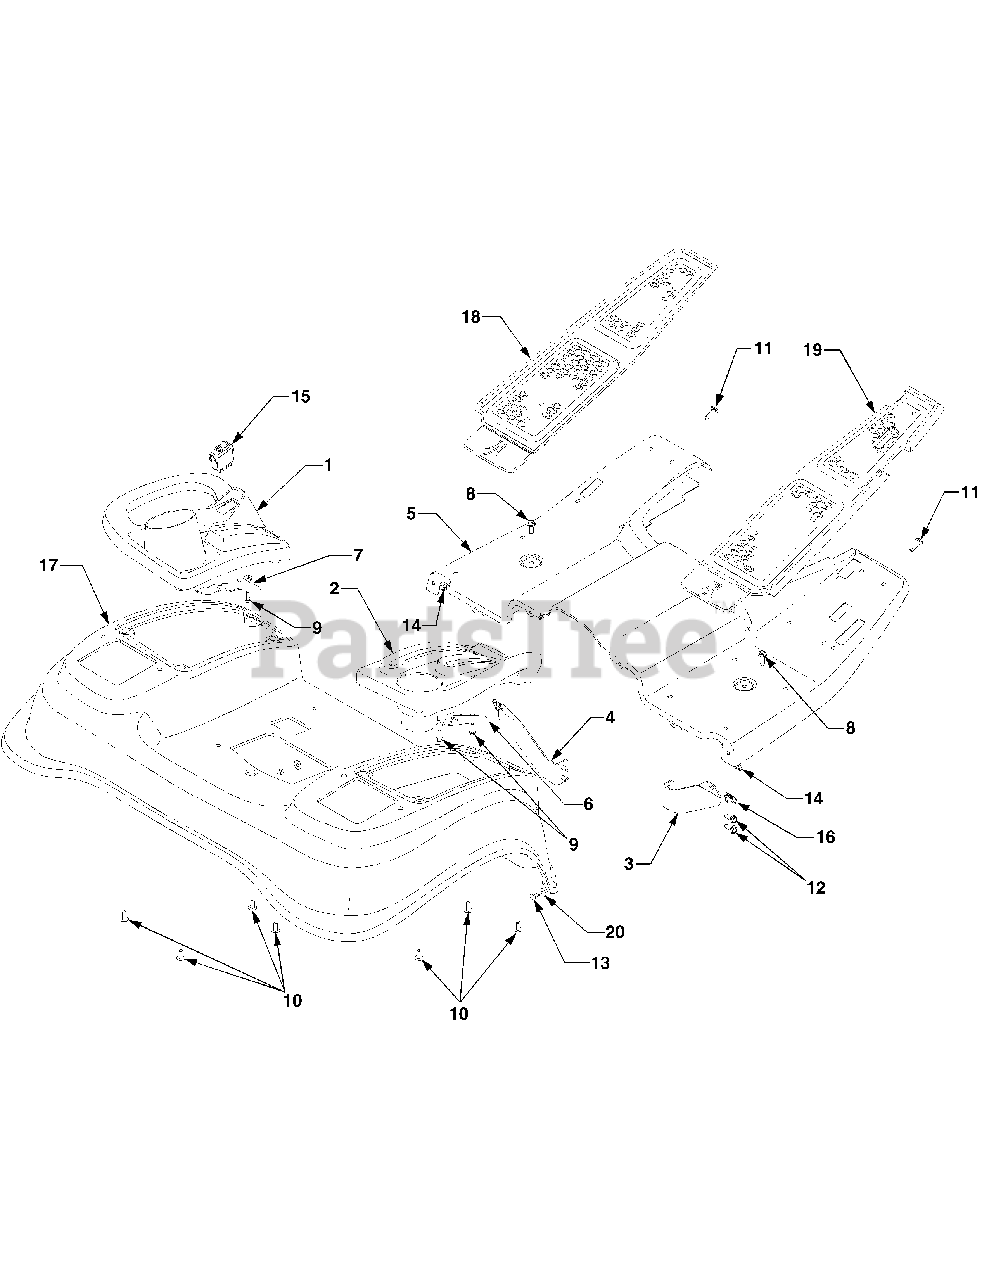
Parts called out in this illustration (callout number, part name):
1	Cover, Fender, LH
2	Cover, Fender, RH
3	Bracket, Running Brd Mtg. RH
4	Bracket, Running Brd Mtg. LH
5	Running Board
5	Graphic, Instruction
5	Graphic, Waring
9	Screw, Hex Wash. Hd, Tapp 1/4-15 x .75
10	Screw, Truss Phillips Hd. 5/16-14 x .75
11	Screw, Pan Hd. 5/16-18 x 1.0 ..
12	Screw, Hex Wash. Hd. Tapp ..5/16-18 x .75
13	Screw, Hx. Cap, 1/4-20 x .5 GR5
14	Nut, Hx. Insert Lck, 1/4-20 GR8
15	Switch, PTO Reverse
16	Nut, Speed, 5/16-18
17	Fender
17	Graphic, Reflector RH
17	Graphic, Reflector LH
17	Graphic, Power Shaft
17	Graphic, Warning
18	Pad, Floor - LH
19	Pad, Floor - RH
20	Washer, Flat, .26 x .72 x .06 ...
